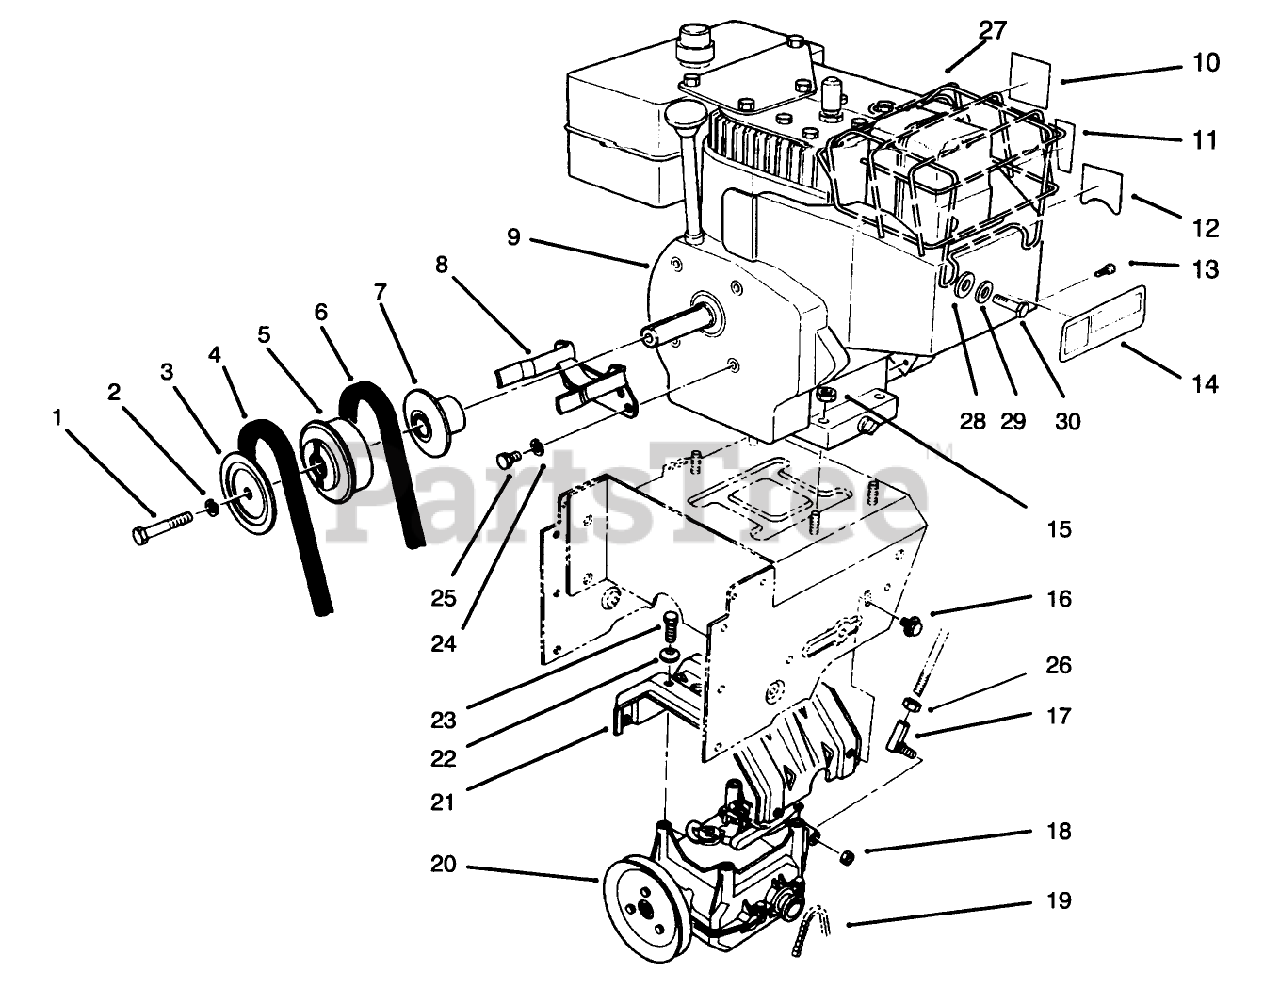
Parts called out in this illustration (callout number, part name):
1	SCREW-HH
2	WASHER-LOCK
3	SHEAVE-HALF, IMPELLER
4	V-BELT
5	PULLEY-ENGINE, CENTER
6	V-BELT, TRACTION
10	DECAL - PRIMER
11	DECAL-THROTTLE
12	DECAL-CHOKE
13	SCREW-HWH
14	DECAL - HOT SURFACE
15	NUT-HF
16	SCREW-HHF
18	NUT-LOCK, NI
20	TRACTION GEARCASE ASM
22	WASHER-SPRING
24	WASHER-LOCK
25	SCREW-HH
26	NUT-HJ
27	Guard-Muffler
28	Washer-Flat
29	Washer-Lock
30	Screw
